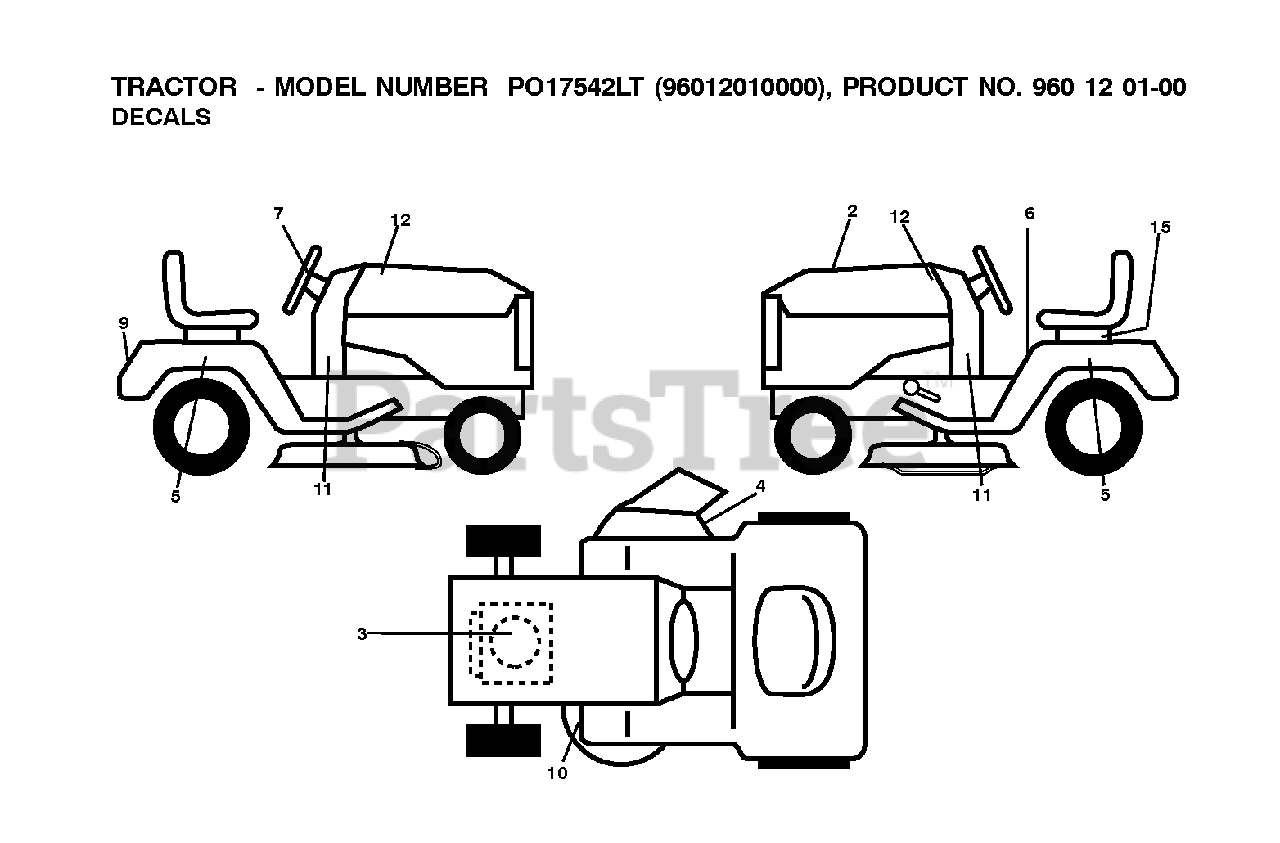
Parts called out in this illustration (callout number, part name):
2	DECAL.RPL.PMST.42C.BS.175.STL
3	DECAL.ENGINE.BS.14.5.PB.278975
4	DECAL.WARN.KEEP.HAND.AWAY
5	DECAL.FEND.RH/LH.SET.6S.POULAN
6	Fender Warning Decal, English
7	DECAL.WHEEL.STRG.STDHRS.POULAN
9	DECAL.FEND.POULAN.2010
10	DECAL V BELT SCHEMATIC
11	DECAL.LWRDASH.145/42.POULAN
12	DECAL.HOOD.ALPHA.RH/LH.POULAN
15	DECAL BTRY SYMBOLS
